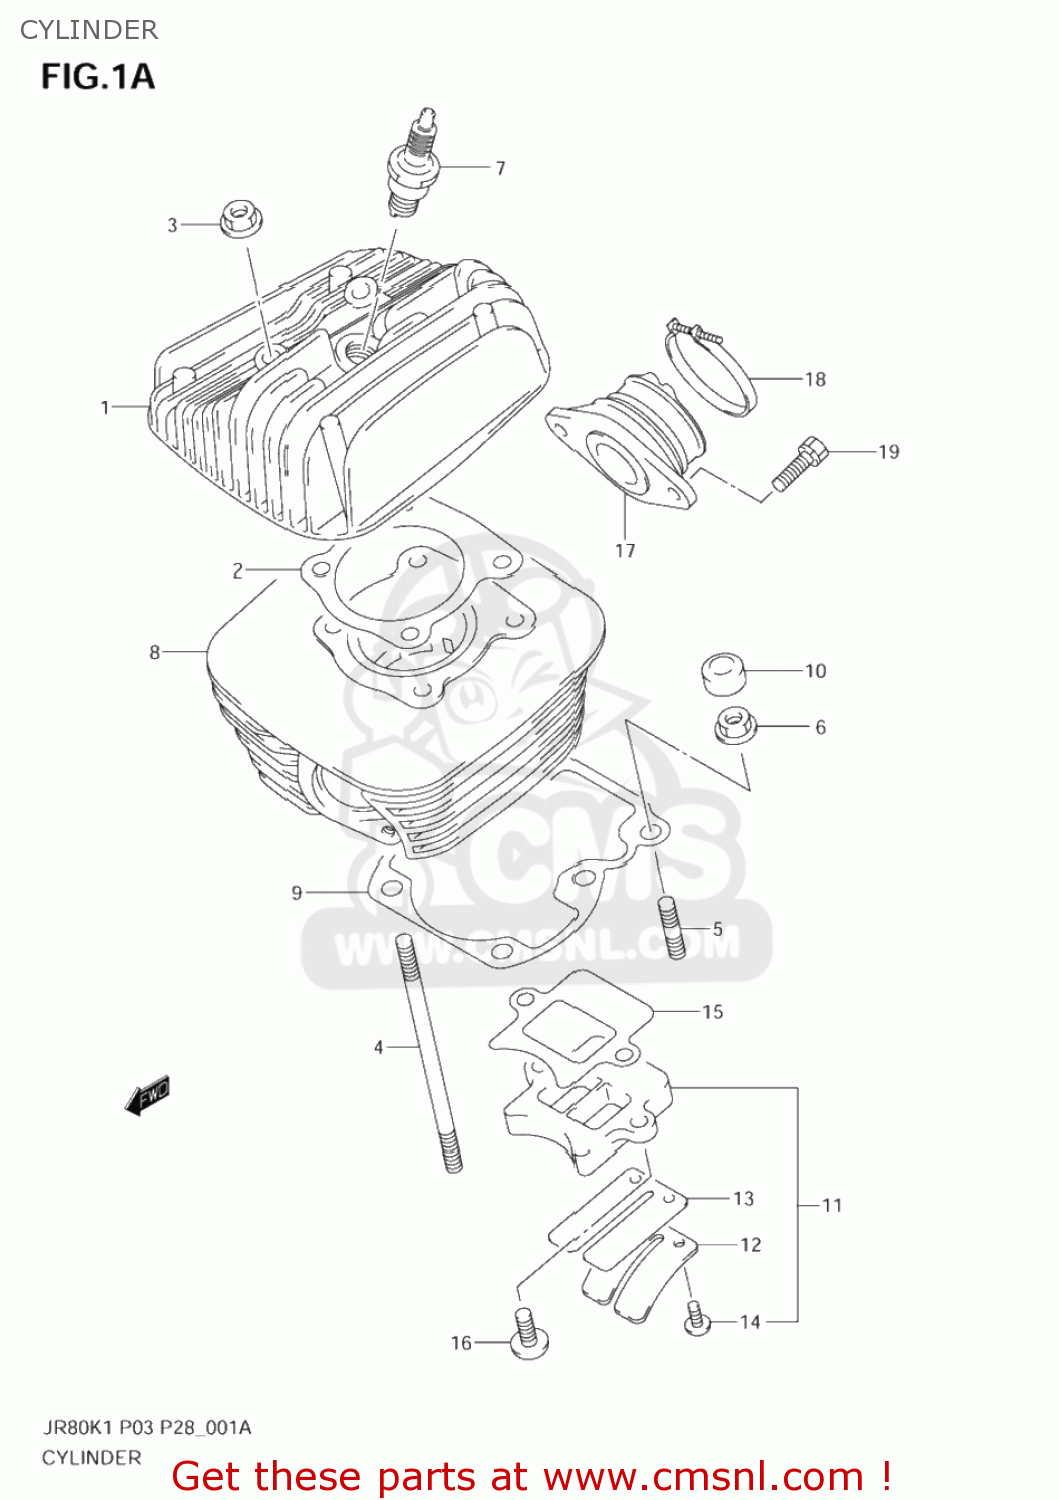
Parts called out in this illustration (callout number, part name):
1	HEAD,CYLINDER
2	GASKET,CYLINDER HEAD (NAS)
3	NUT
4	BOLT,STUD
5	STUD,M6X1X32
6	NUT
7	PLUG,SPARK(BR7ES)
8	CYLINDER
9	GASKET,CYLINDER (NAS)
10	PAD,CYLINDER RUBBER(N1)
11	VALVE ASSY,REED
12	STOPPER,REED VALVE
13	VALVE,REED
14	SCREW
15	GASKET,REED VALVE (NAS)
16	SCREW 6X16
17	PIPE,INTAKE
18	CLAMP
19	BOLT
